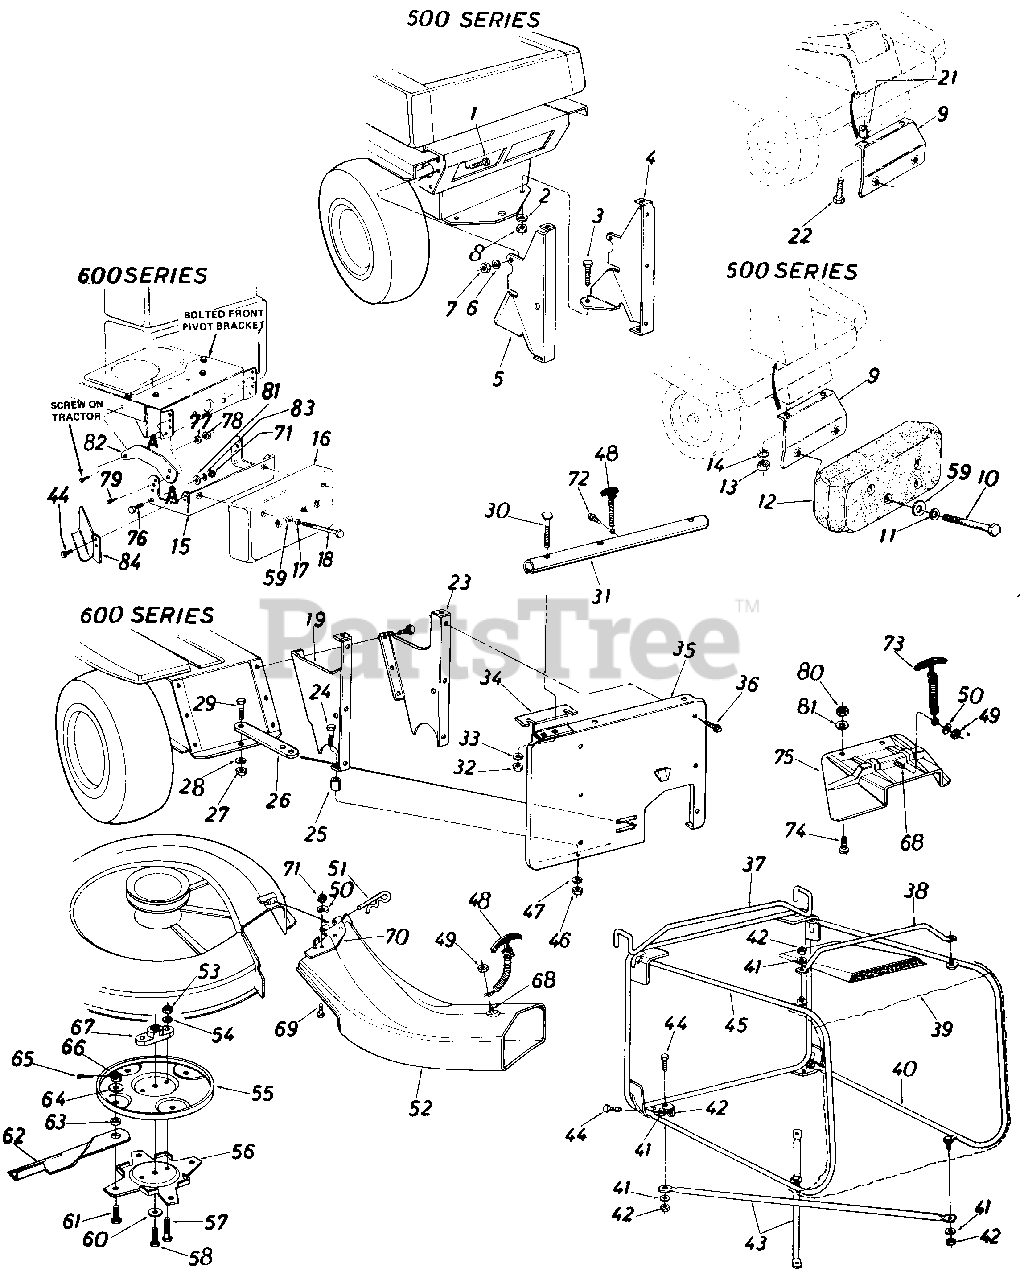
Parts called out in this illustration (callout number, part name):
1	Hex Bolt 5/16-18 x 1.00" Lg. *
2	L.-Wash. 5/16" I.D.*
3	Hex Bolt 5/16-18 x 1.00" Lg.*
4	Catcher Support Brk't.-R.H.
5	Catcher Support Brk't.-L.H.
6	L.-Wash. 5/16"1.D.*
7	Hex Nut 5/16-18 Thd.*
8	Hex Nut 5/16-18 Thd. *
9	Counterweight Support Brk't. Ass'y.
10	Hex Bolt 3/8-16 x 4.5" Lg.*
11	Belleville Wash. .400" I.D. x .88" O.D.
12	Counterweight 38 Ibs.
13	Hex Nut 5/16-18 Thd.*
14	L.-Wash. 5/16"1.D.*
15	Counterweight Support Brk't. Ass'y.
16	Counterweight 38 lbs.
17	Belleville Wash. .400" I.D. x .88" O.D.
18	Hex Bolt 3/8-16 x 4.5" Lg.*
19	Catcher Support Brkt.-L.H
21	Spacer.380" I.D. x 1. 00" O.D. x .320" Lg.
22	Not Part of Kitt
23	Catcher Support Brk't.-R.H.
24	Hex Bolt 5/16-18 x 1.50" Lg *
25	Spacer .380" I.D. x .47" O.D. x 1.00"Lg.
28	L.-Wash. 1/2" I.D.
29	Hex Bolt 1/2-20 x 1.00" Lg.*
30	Curved Carriage Bolt 5/16-18 x 1.75" Lg.
33	L.-Wash. 5/16" I.D.*
34	Grass Catcher Support Plate
35	Rear Discharge Panel
36	Hex Wash. Hd. Self Tap. Scr. 1/4 x 20 x .50
37	Grass Catcher Frame Ass'y..30"
42	Hex L.-Nut 1/2-20 Thd.
43	Bottom Cross Brace 26.62
44	Hex Bolt 1/4-20 x .62" Lg.*
47	L.-Wash. 5/16" I.D.*
48	Hook Latch Ass'y.
49	Hex L.-Nut 1/4-20 Thd.
50	Fl.-Wash. 1/4 " I. D. *
51	Not Part of Kitt
52	R.D. Banana Chute Ass'y.
53	Hex Nut 5/16-24 Thd.*
54	L.-Wash. 5/16" I.D.*
55	Upper Blade Disc.
58	Hex Bolt 3/8-24 x 1.00" Lg.
59	Fl.-Wash....39" I.D. x 1.12" O.D.
60	Bell.-Wash...39" I.D. x 1.38" O.D.
61	Shld. Bolt. .500" Dia. x .360 Spec.
62	30" Blade Tip
63	Spacer. 505" I.D. x .750" O.D. x 1.25" Lg.
64	Fl.-Wash500" I.D. x 1.25" O.D.
65	Cotter Pin 3/32" Dia. x 1.00" Lg.*
66	Hex Slotted Nut 1/2-20 Thd.
67	Blade Adapter
68	Hex Bolt 1/4-20 x .50" Lg.*
69	Truss Mach. Scr. 1/4-20 x.50" Lg.*
72	Hex "AB"-Tap Scr. 1/4 x .62" Lg.
73	Hook Latch Ass'y. x 7.0" Lg.
74	Truss Mach. Scr. 1/4-20 x .50" Lg. 4
75	R D Chute Extension
76	Hex Bolt 7/16-14 x 1.00" Lg.*
77	L.-Wash. 7/16" I.D.4
78	Hex Nut 7/16-14 Thd.*
79	Self-Tap Scr. 5/16-18 x 1.0" Lg.
80	Hex L.-Nut 1/4-20 Thd.
81	Fl. Wash. .281" I.D. x .50" O.D. x .063
82	Tie Strap
83	L-Wash. 1/4" I.D.*
84	Exhaust Deflector
